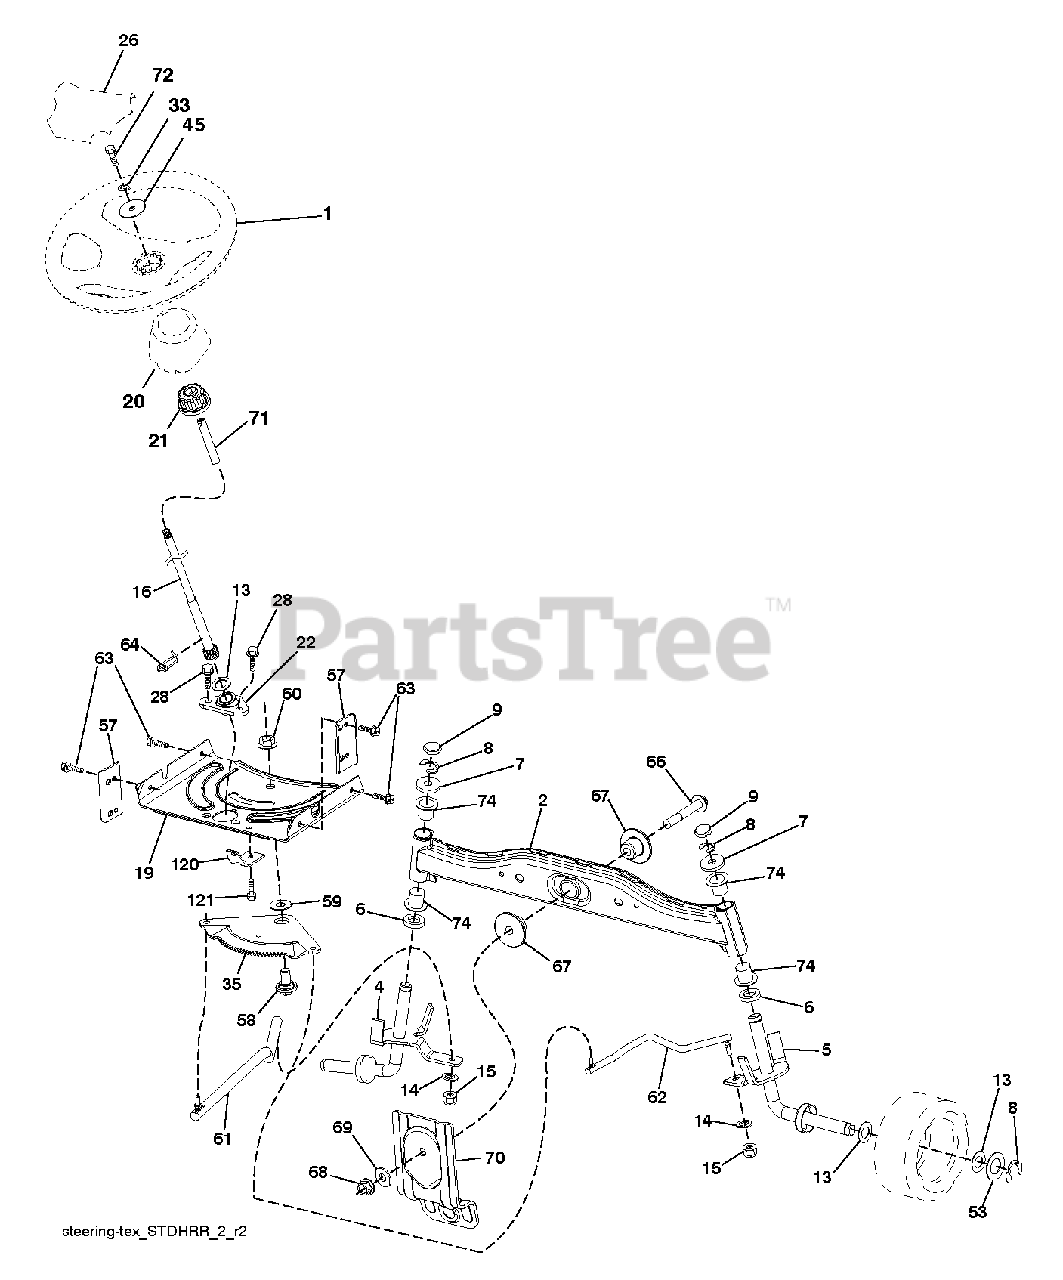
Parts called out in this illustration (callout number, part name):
1	WHEEL.STEERING.HARD.RIM.BLAC
2	AXLE HALF ASM-WELDED
4	SPINDLE.WELDED.LH.15"TEX
5	SPINDLE.WELDED.RH.15"T
8	RING CLIP
9	CAP.SPINDLE.BLACK
14	WASHER, LOCK 3/8
15	NUT CROWNLOCK 3/8-24
16	SHAFT.STEER.3/4.NON-PLATED.TEX
19	PLATE.STEER.DDL.NLT/NG
20	BOOT STEERING BLACK
21	ADAPTER, WHEEL STNG..
22	STEERING.SUPT.LOWER.
26	INSERT, WHEEL STEERING
28	SCREW, 3/8-16X3/4
33	LOCKWASHER
35	GEAR.SECTOR.PLATE.DDL.
45	WASHER.11/32
53	WASHER.HARDENED
57	BRACKET.UPSTOP.TEX
58	BOLT.SHOULDER.SECTOR.P
59	WASHER.THURST.SECTOR.S
60	NUT FLANGE LOCK 5/8-11
61	DRAGLINK.LH.BALLSTUD.D
62	DRAGLINK.RH.BALLSTUD.D
63	SCREW
64	RETAINER.CLIP.SPRING.S
66	BOLT HEX FGHD 7/16-14 X 3 SERR
67	BUSHING.PM.FRONT AXLE
68	NUT.LOCK.FLANGE.7/16
69	WASHER.1.5X.505X.118
70	BRKT.DECK.SUSPENSION.F
71	SHAFT.EXTEN.STRG.SPLINE
72	BOLT 5/16-18 X 4 W/PATCH
74	Steering Column Bearing
120	BRKT.LOCATOR.CBL.BRAKE.VARIATO
121	SCREW LT
